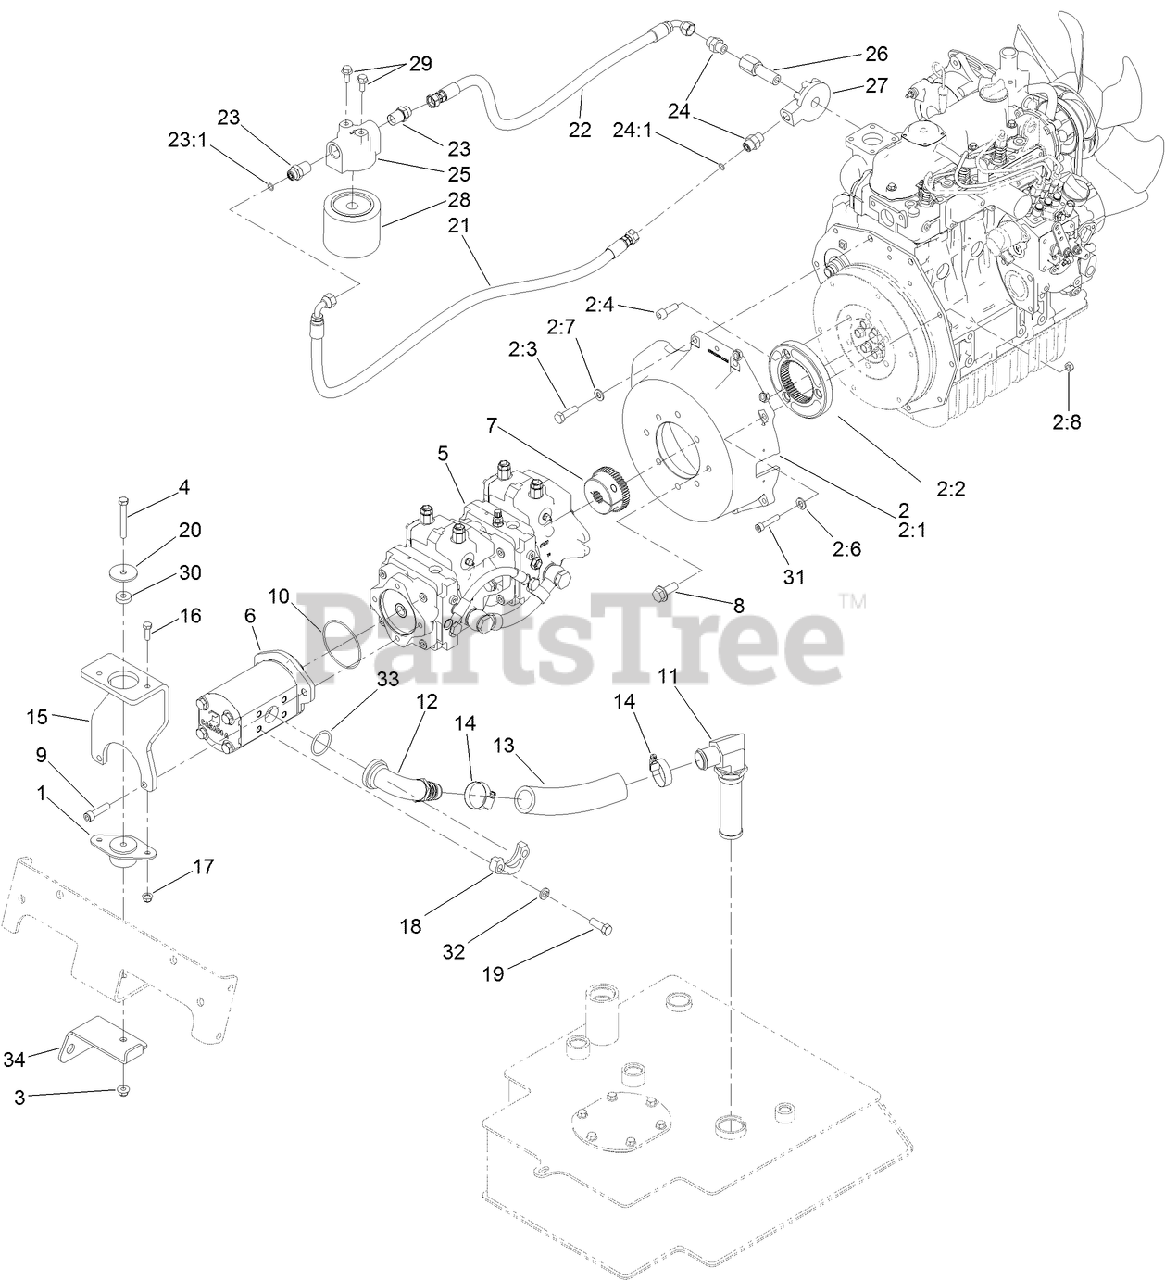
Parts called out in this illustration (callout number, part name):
1	MOUNT-ENGINE
2	MOUNT-PUMP
2:1	HOUSING-PUMP MOUNT
2:2	FLANGE-COUPLER
2:3	SCREW-HH
2:4	SCREW-HSH
2:6	WASHER-PLAIN
2:7	WASHER-FLAT
2:8	NUT-HEX
3	NUT-HF, NI
4	SCREW-HH
5	PUMP-TANDEM
6	PUMP-GEAR
7	HUB-PUMP
8	SCREW-HHF
9	SCREW-SH
10	O-RING
11	STRAINER-SUCTION
12	FITTING
13	HOSE-SUCTION
15	BRACKET-SUPPORT, PUMP
16	SCREW-HH
17	NUT-HF, NI
18	FLANGE
19	SCREW-HH
20	WASHER-REBOUND
21	HOSE-HYD
22	HOSE-HYD
23	FITTING-HYD
23:1	O-RING
24	FITTING-HYD
24:1	O-RING
25	BASE-FILTER
26	PIPE-JOINT
27	BASE-FILTER
28	FILTER-OIL
29	SCREW-HHF
30	SPACER
31	SCREW-HSH
32	WASHER-LOCK
33	O-RING
34	BRACKET-BULKHEAD
